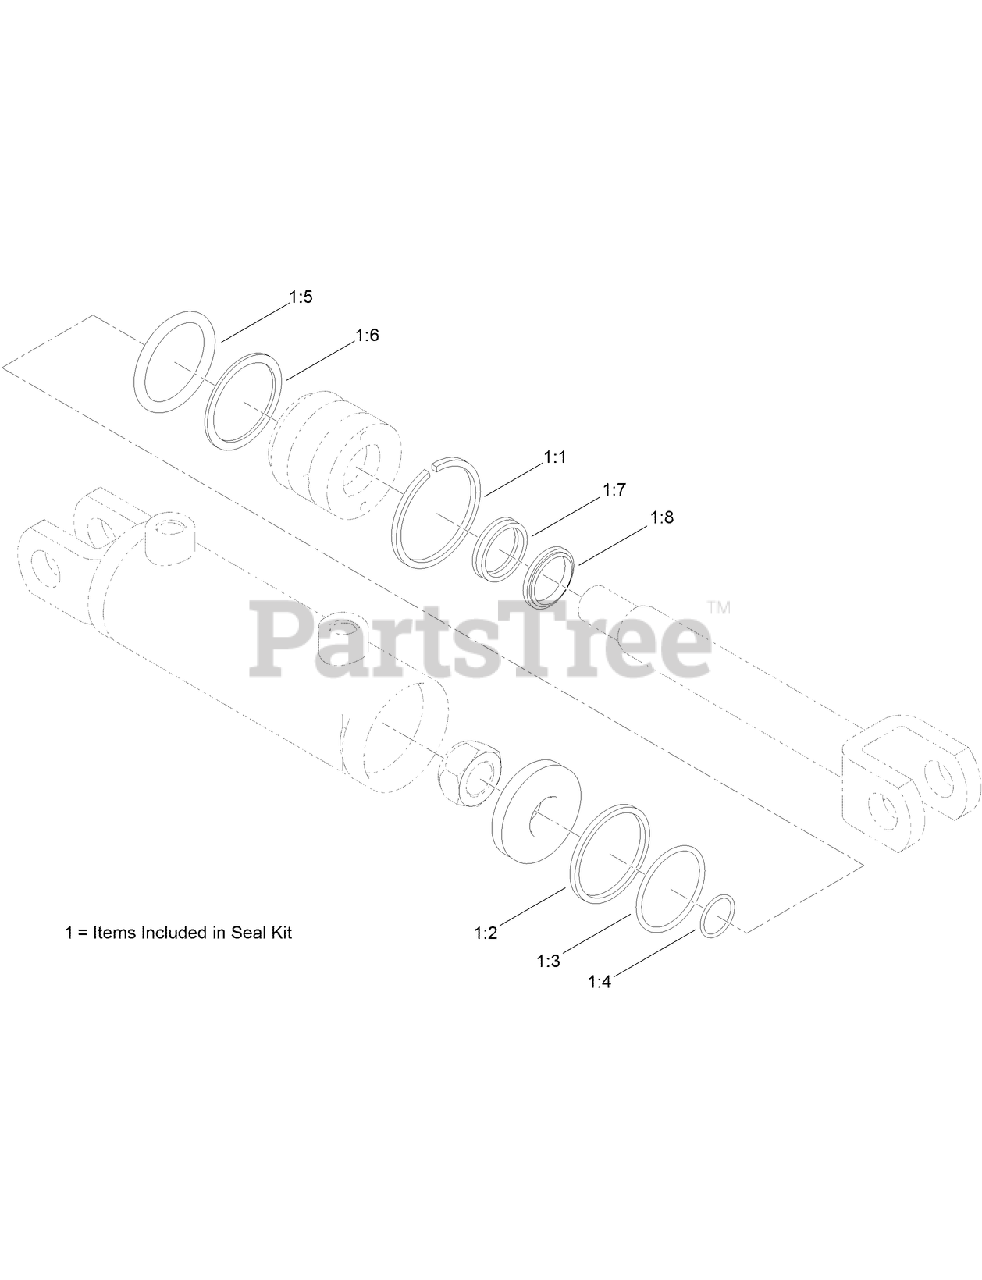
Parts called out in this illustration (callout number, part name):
1:1	RING-RETAINING
1:2	Seal-Teflon
1:3	O-RING
1:4	O-RING
1:5	O-RING
1:6	Washer-Back Up
1:7	Seal-U Cup
1:8	WIPER
